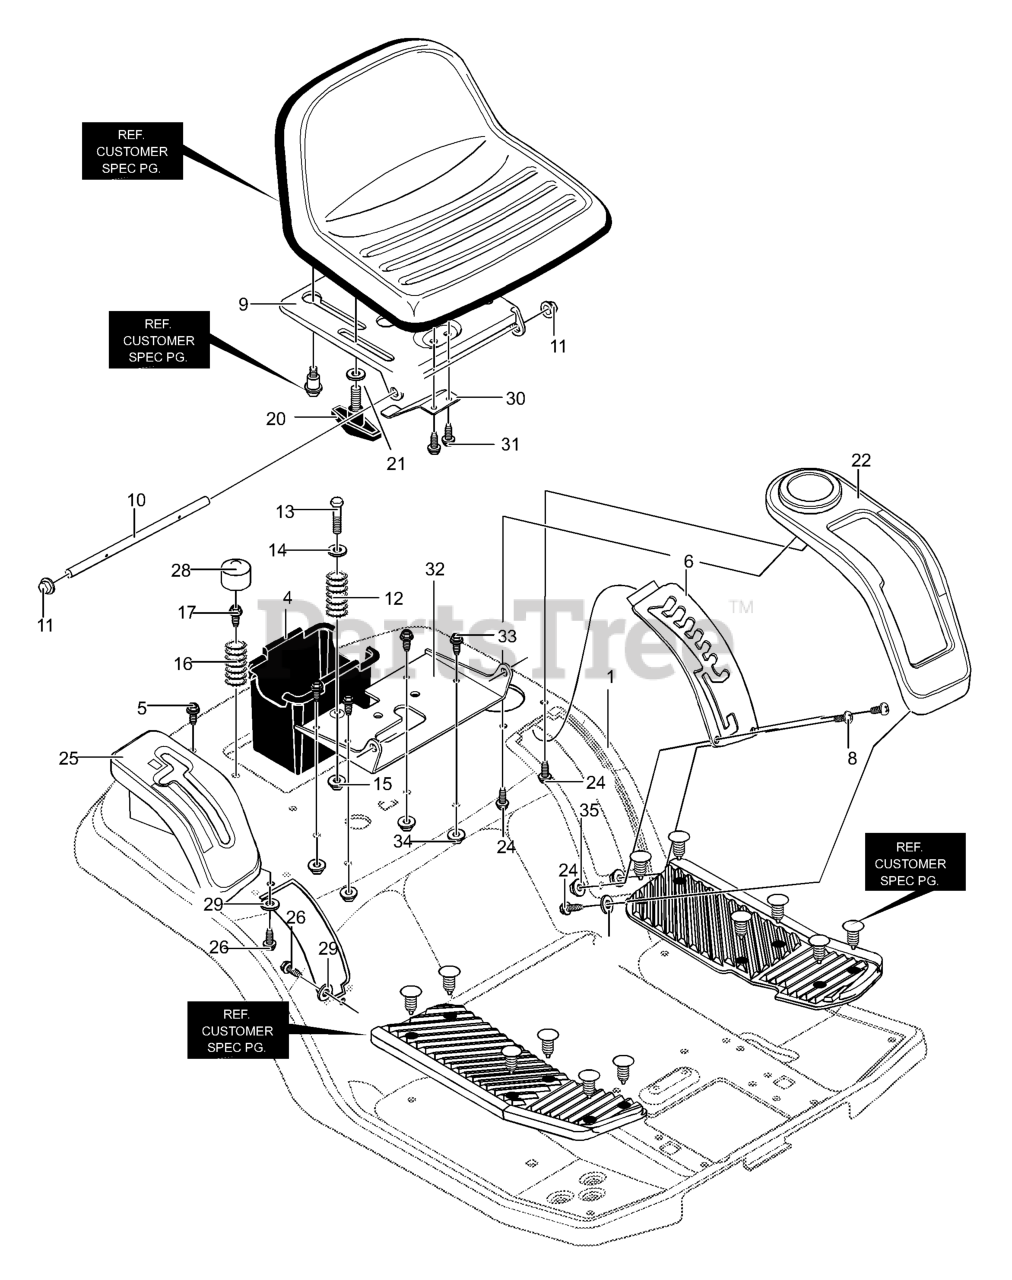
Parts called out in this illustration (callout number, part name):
1	Seat Deck
4	Battery Container
5	Screw, 1/4-20x.63
6	Plate, Lift Detent
8	Screw, 10-24x.500
9	Seat Support
10	Hinge, Seat Pivot
11	Push Cap Nut
12	Comp. Spring
13	Shoulder Bolt, 1/4-20
14	Washer Cup
15	Nut, 1/4-20
16	Comp. Spring
17	Screw, 5/16-18 x 0.75
20	Wing Bolt 5/16-18x.50
21	Washer
22	Detent Cover w/cup
24	Screw, 1/4-15
25	Shift Cover Hand/Foot
26	Screw, 1/4-15x.44
27	Flat washer
29	Flat washer
30	Spring - Leaf
31	Screw, 1/4-20x.50
32	Bracket, Pivot Seat
33	Screw, 5/16-18 x 0.75
34	Nut, 5/16-18 Wdfllk
35	Nut, #10-24 Locknut
